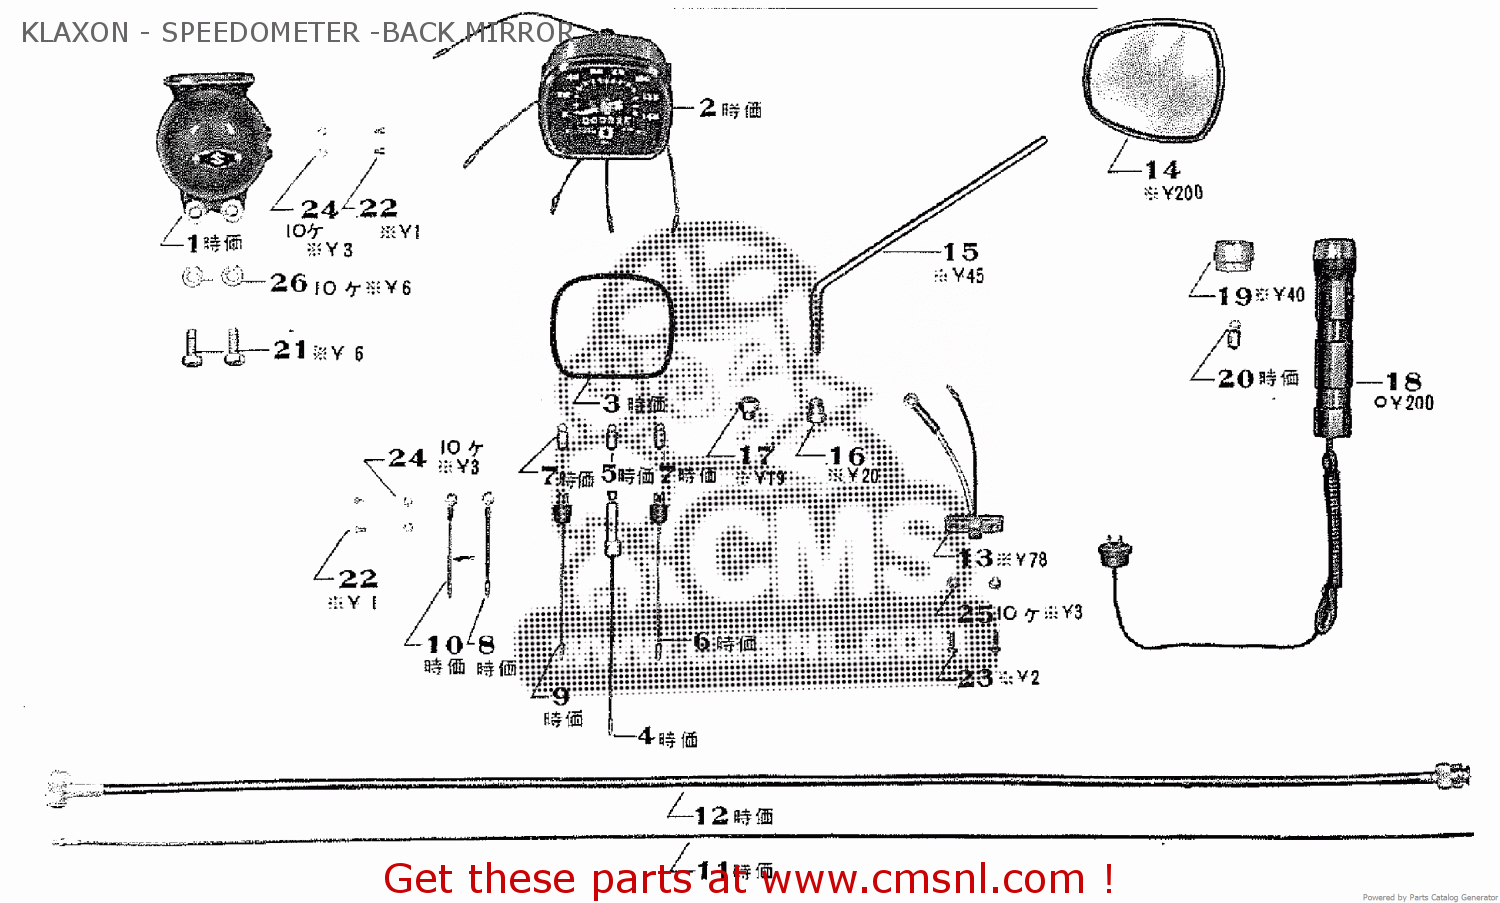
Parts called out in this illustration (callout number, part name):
1	KLAXON ASSY.
2	SPEEDOMETER ASSY.
3	SPEEDOMETER SET PACKING
4	PILOT LAMP SOCKET COMP.
5	SPEEDOMETER LAMP VALVE
6	NEUTRAL LAMP SOCKET COMP.
7	NEUTRAL AND CHARGE LAMP VALVE
8	NEUTRAL LAMP EARTH CORD
9	CHARGE LAMP SOCKET COMP.
10	CHARGE LAMP EARTH CORD
11	SPEEDOMETER INNER CABLE
12	SPEEDOMETER OUTER CABLE
13	BACK MIRROR ASSY.
14	BACK MIRROR COMP.
15	BACK MIRROR ARM
16	BACK MIRROR SET NUT
17	BACK MIRROR PLUG
18	REPAIR LAMP ASSY.
19	REPAIR LAMP LENS
20	REPAIR LAMP VALVE
21	8X20 HEXAGON BOLT
22	3X5 CROSS SCREW
23	5X12 CROSS SCREW
24	8MM SPRING WASHER
25	5MM SPRING WASHER
26	8MM SPRING WASHER
